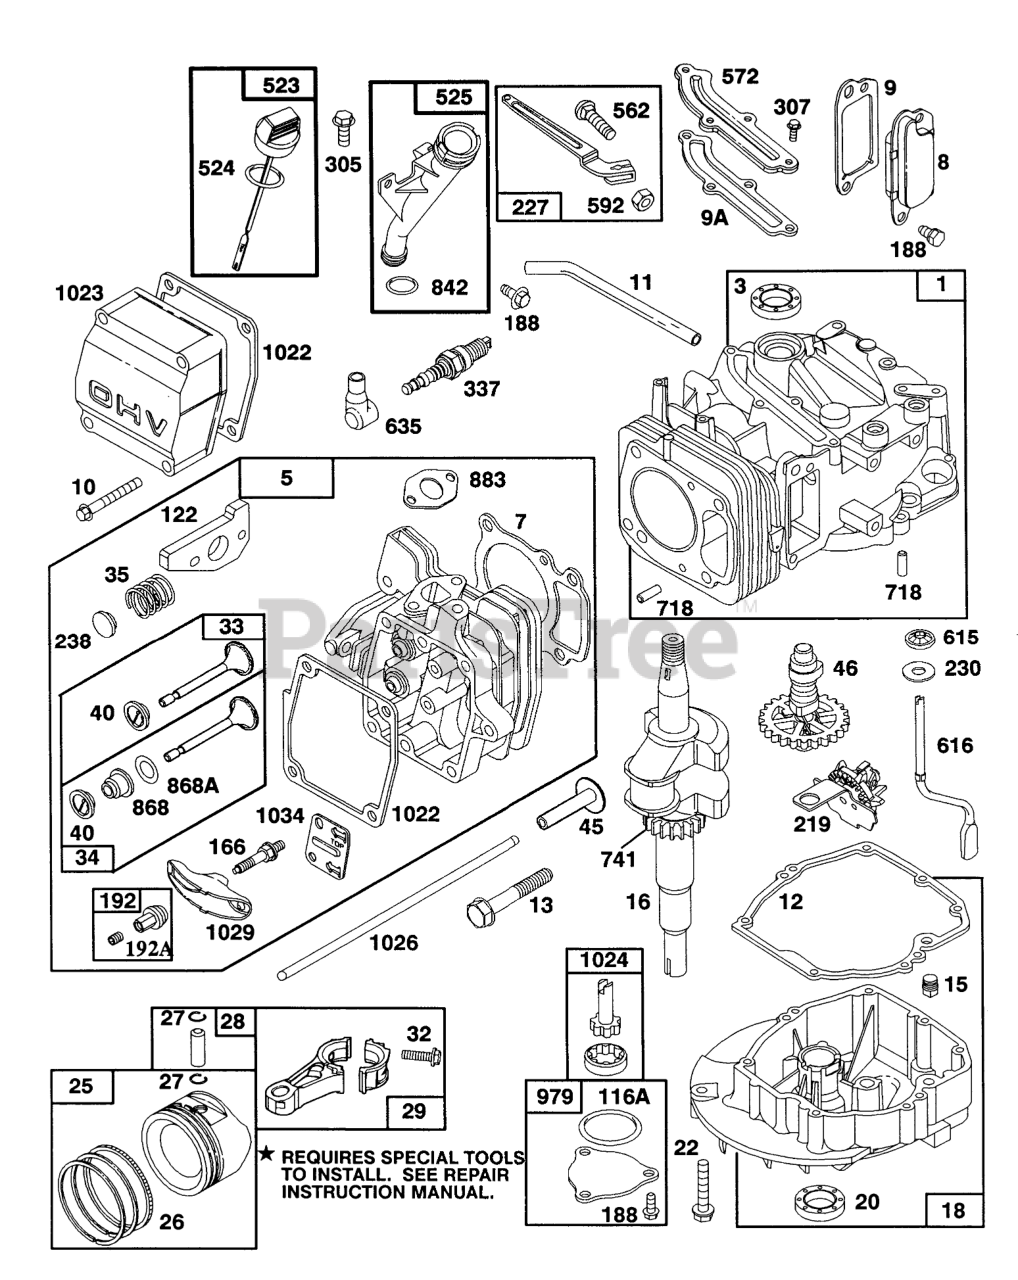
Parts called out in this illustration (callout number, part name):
1	CYLINDER ASSEMBLY
3	SEAL - OIL
5	CYLINDER HEAD
7	CYLINDER HEAD GASKET
8	Breather Assy
9	Gasket-Breather
9A	GASKET-BREATHER
10	HEX HEAD SCREW
11	BREATHER TUBE
12	ENGINE BASE GASKET
13	CYLINDER HEAD SCREW
15	PLUG - OIL DRAIN
16	CRANKSHAFT
18	ENGINE SUMP
20	SEAL-OIL
22	SCREW - ENGINE BASE
25	STD PISTON ASSEMBLY
26	STD RING SET
27	PISTON PIN LOCK
28	Pin Assy-Piston
29	CONNECTING ROD
32	Connecting Rod
33	EXHAUST VALVE
34	INTAKE VALVE
35	VALVE SPRING
40	SPRING RETAINER
45	VALVE TAPPET
46	CAM GEAR
116A	O RING SEAL
122	ADAPTER ASSEMBLY
166	ROCKER ARM STUD
188	SCREW - SEM
192	NUT - HEX SPECIAL
192A	Screw-Set
219	GOVERNOR/OIL SLINGER
227	GOVERNOR LEVER ASSEMBLY
230	WASHER
238	VALVE CAP
305	SCREW - HEX HEAD
307	SCREW - SEM
337	PLUG-SPARK
523	DIPSTICK-OIL
524	O-RING
525	OIL FILLER TUBE
562	GOVERNOR LEVER BOLT
572	BAFFLE - CYCLINDER
592	HEX NUT
615	FASTENER
616	GOVERNOR CRANK
635	SPARK PLUG ELBOW
718	DOWEL - SLEEVE
741	TIMING GEAR
842	O-RING
868	SealAssy-Valve
868A	Seal-Valve
883	EXHAUST GASKET
979	OIL PUMP COVER
1022	ROCKER COVER GASKET
1023	Cover-Valve
1024	OIL PUMP
1026	PUSH ROD
1029	ROCKER ARM
1034	PUSH ROD GUIDE
